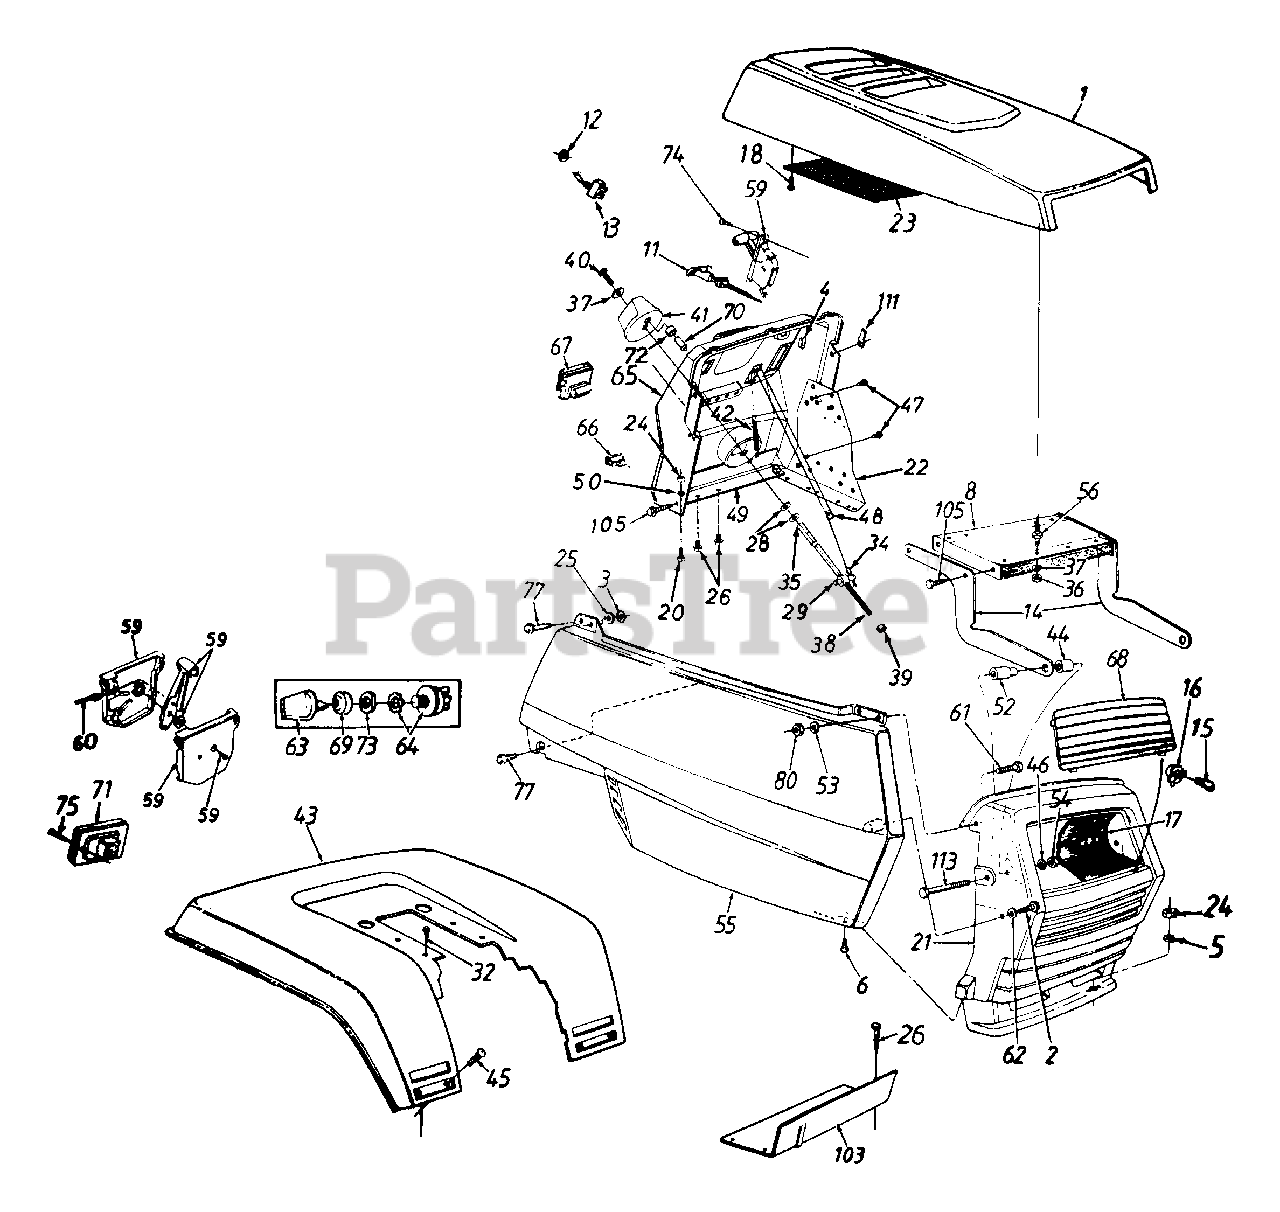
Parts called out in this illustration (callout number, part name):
1	Hood
2	Hex Wash. B-Tap Scr. 1/4 x .62" Lg.
3	Bolt Retainer 1/4" I.D.
4	Retainer Clip
6	Truss Mach. B-Tap Scr. #10 x .5" Lg.
12	Hex Nut 1/2-27 Thd. (LT-165)
13	Toggle Switch (LT-165)
16	Twist Lock - Lamp Socket
17	Reflector - Headlight
18	Hex Wash. Hd. AB-Tap Scr. #8 x .5" Lg.
20	Hex Bolt 5/16-18 x .75" Lg.
21	Grille
24	Hex Sems Nut 5/16-18 Thd.
25	Fl-Wash. 1/4" I.D. x .93" O.D.
26	Hex Wash. Hd. B-Tap Scr. 5/16-18 x .5" Lg.
28	Fl-Wash. 3/8" I.D. x .875" O.D.
29	Adj. Ferrule 3/8-8 Thd.
34	Hairpin Clip
35	"E"-Ring .375" Dia.
36	Hex Nut 1/4-20 Thd. (Gr. 5)
37	Bell-Wash. .265" I.D. x .75"
38	Adjustment Rod
39	Hex Nut 3/8-8 Twin Thd.
40	Hex Bolt 1/4-20 x .75" Lg.
41	Plastic Knob
42	Ext. Spring 3.21" Lg.
45	Carriage Bolt 1/4-20 x .50" Lg.
46	Fl-Wash. .328" I.D. x .68" O.D.
47	Hex Wash. Hd. Scr. 1/4-20 x .5" Lg.
48	Indicator Strip
52	Shld. Spacer .33" I.D.
53	Fl-Wash. .281" I.D. x .5" O.D.
54	Hex Cent. L-Nut 5/16-18 Thd.
55	Side Cover - R.H.
56	Double Ended Stud 1/4-20 Thd.
59	Throttle Control Box Ass'y.
60	Throttle Control Wire 22" Lg.
61	Hex Bolt 1/4-20 x .62" Lg.
62	Fl-Wash. .281" I.D. x .73" O.D.
64	Ignition Switch
65	Dash Panel
66	Light Switch
67	Ammeter
68	Lens
69	Ignition Switch Cap
70	Ball Plunger
71	Tail light (LT-165)
73	Ignition Switch Nut
74	Truss Mach. AB-Tap Scr. #10 x .5" Lg.
75	Truss Hd. AB-Tap Scr. #6 x .62" Lg. (LT 165)
77	Hex Wash. Hd. Tap Scr. 1/4 x .75" Lg.
80	Hex L-Nut 1/4-20 Thd.
111	Speed Nut 1/4-20 Thd.
113	Hex Bolt 5/16-18 x 2.75"
